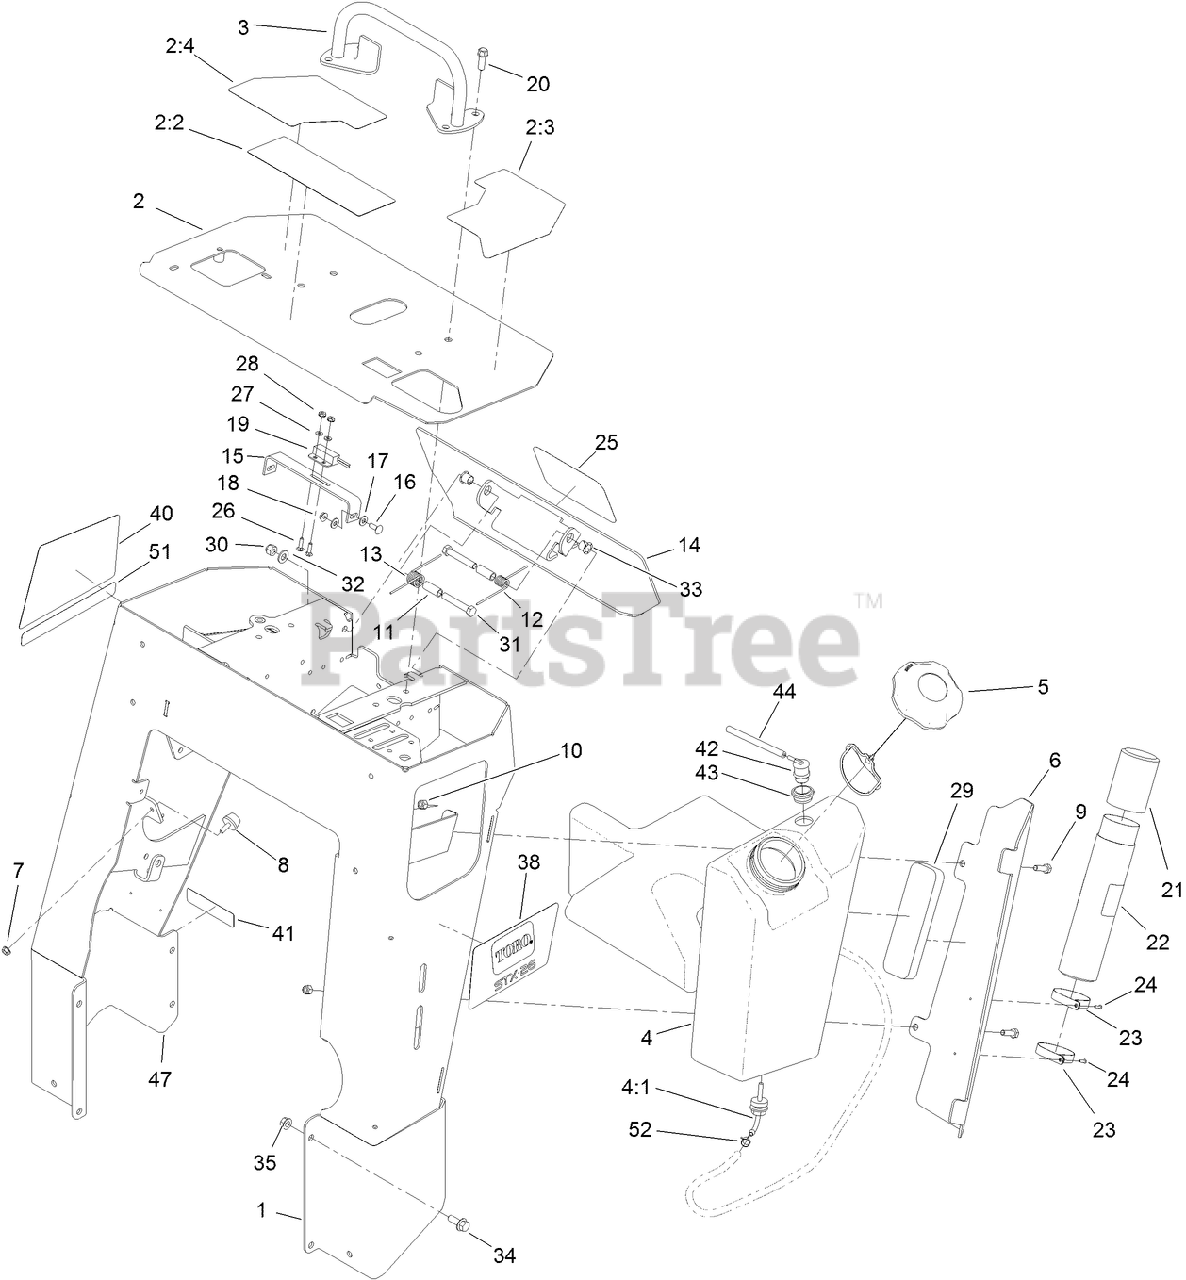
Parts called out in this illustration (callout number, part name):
2	CONTROL PANEL ASM
2:2	DECAL-WARNING
2:3	DECAL-CONSOLE, LH
2:4	DECAL-CONSOLE, RH
3	BAR-REFERENCE
4	TANK-FUEL
4:1	FITTING-FUEL, BULKHEAD
5	CAP-FUEL, RATCHETING
6	BRACKET-COVER, TANK
7	NUT-HF
8	BUMPER
9	SCREW-HH
10	NUT-LOCK, NI
11	SPACER-SPRING
12	SPRING-TORSION, LH
13	SPRING-TORSION, RH
14	PLATE-REVERSE
15	PLATE-SWITCH
16	BOLT-CARR
17	WASHER-FLAT
18	NUT-KEPS
19	SWITCH-PROXIMITY
20	SCREW-TAPTITE
21	CAP-HOUSING
22	TUBE-MANUAL
23	CLAMP-R
24	RIVET-POP
26	SCREW-CARR
27	WASHER-FLAT
28	NUT-KEPS
29	PAD-FOAM
30	NUT-LOCK, NI
31	SCREW-HH
32	WASHER-FLAT
33	BUSHING-NYLINER
34	SCREW-HHF
35	NUT-FLANGE
38	DECAL-SIDE, LH
40	DECAL-SIDE, RH
41	DECAL-ARRESTER, SPARK
42	VALVE-ROLLOVER
43	GROMMET
44	HOSE-VENT, TANK
47	DECAL-POINT, LIFT
51	DECAL-INTELLISWEEP
52	CLAMP-HOSE
